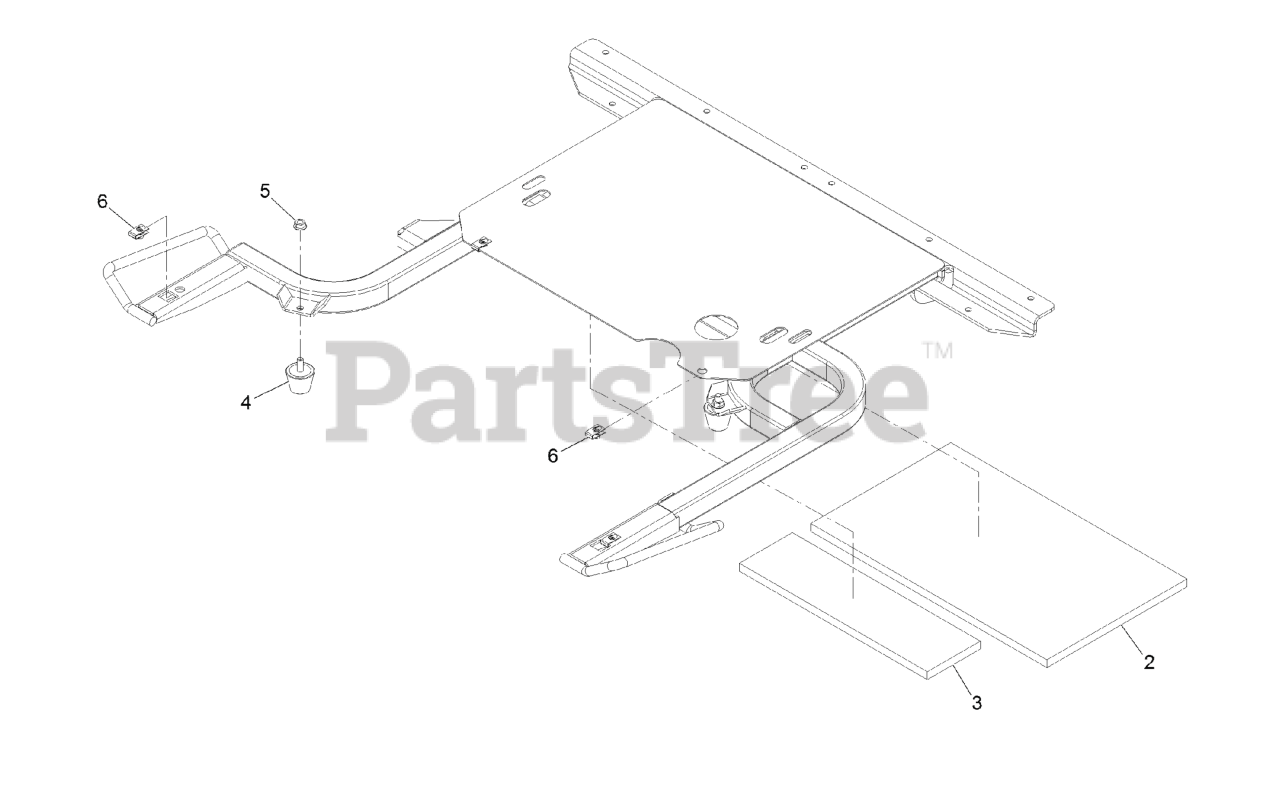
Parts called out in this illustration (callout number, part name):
2	INSULATION-FOAM PAD, REAR
3	INSULATION-FOAM PAD, FRON
4	BUMPER-RUBBER
